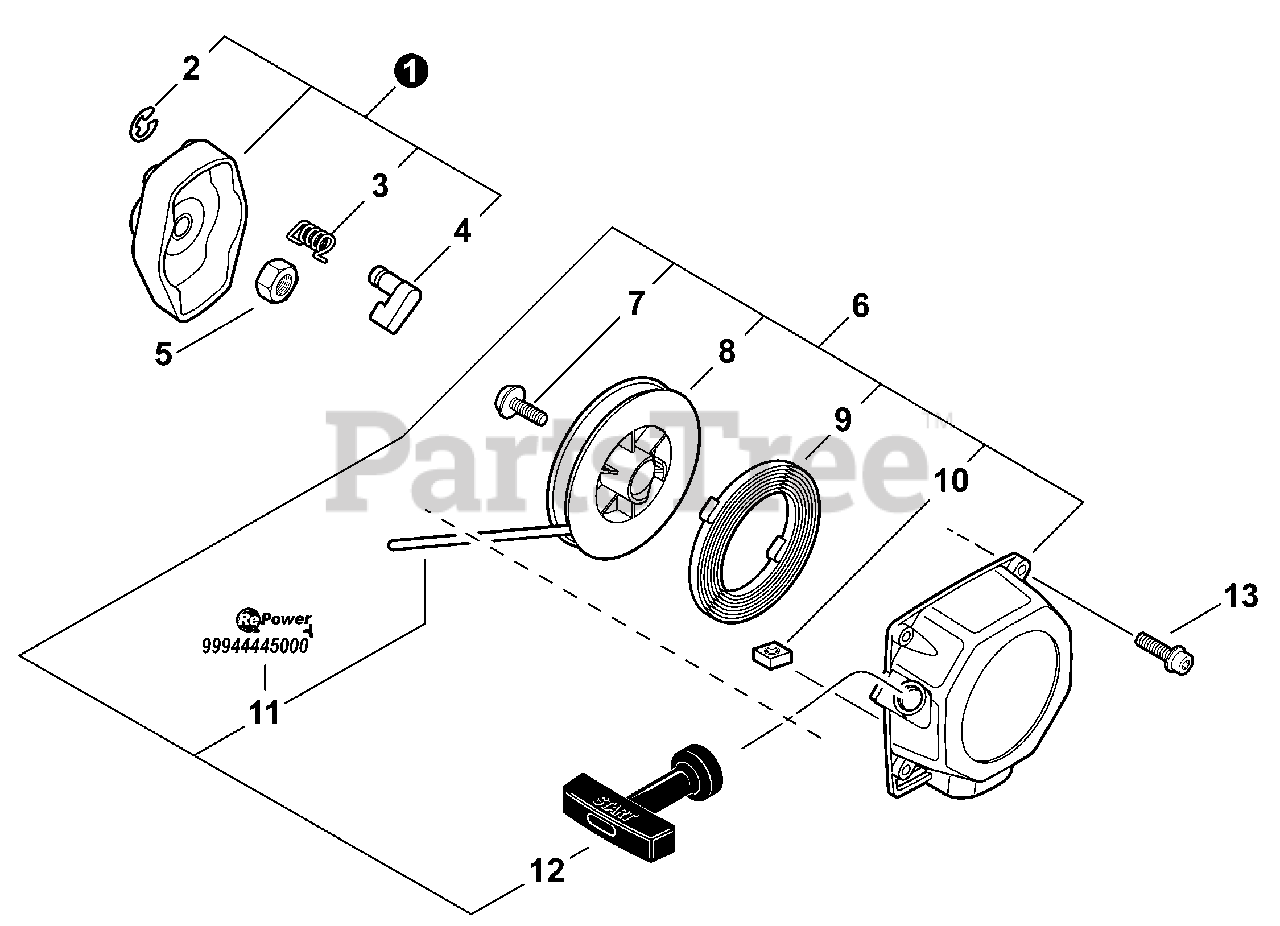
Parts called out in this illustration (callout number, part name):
1	STARTER PAWL ASY
2	RING, RETAINING - 4
3	SPRING, RETURN
4	PAWL, STARTER
6	STARTER ASY
8	REEL, ROPE
9	SPRING, REWIND
10	NUT
11	ROPE, STARTER - 3.5×900
12	GRIP, STARTER
13	SCREW - 5X16
